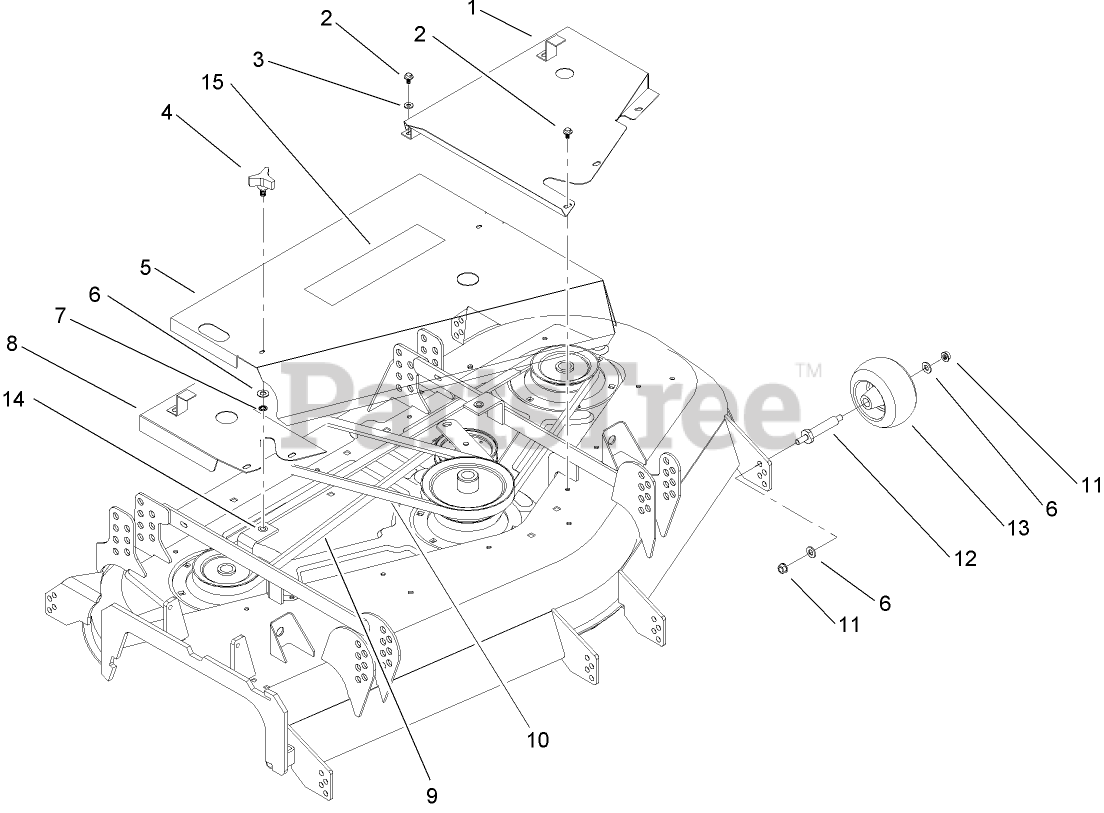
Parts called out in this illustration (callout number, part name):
1	LH COVER ASM
2	SCREW-HWH
3	WASHER-FLAT
5	COVER-CENTER
6	WASHER-FLAT
7	RING-RETAINING
8	RH COVER ASM
9	V-BELT
10	V-BELT-DECK DRIVE
11	NUT-LOCK, NI
12	SPACER
13	WHEEL-GAGE
14	INSERT-NUT
